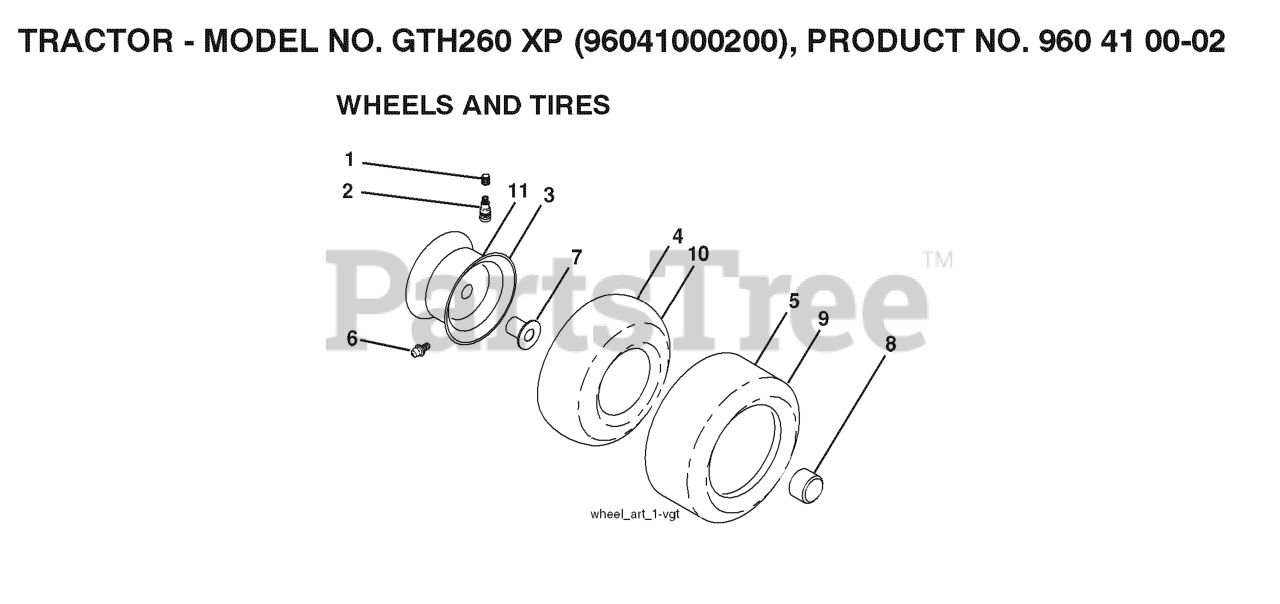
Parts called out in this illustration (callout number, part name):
2	VALVE STEM LT
3	RIM ASSEMBLY, FRONT
4	TUBE.5.3/4.5/6
5	TIRE HEAVY DUTY
6	FITTING LT
7	BEARING T
8	CAP, AXLE BLK
9	TIRE HEAVY DUTY
10	TUBE
11	RIM.ASM.12X7.REAR.SILVER
